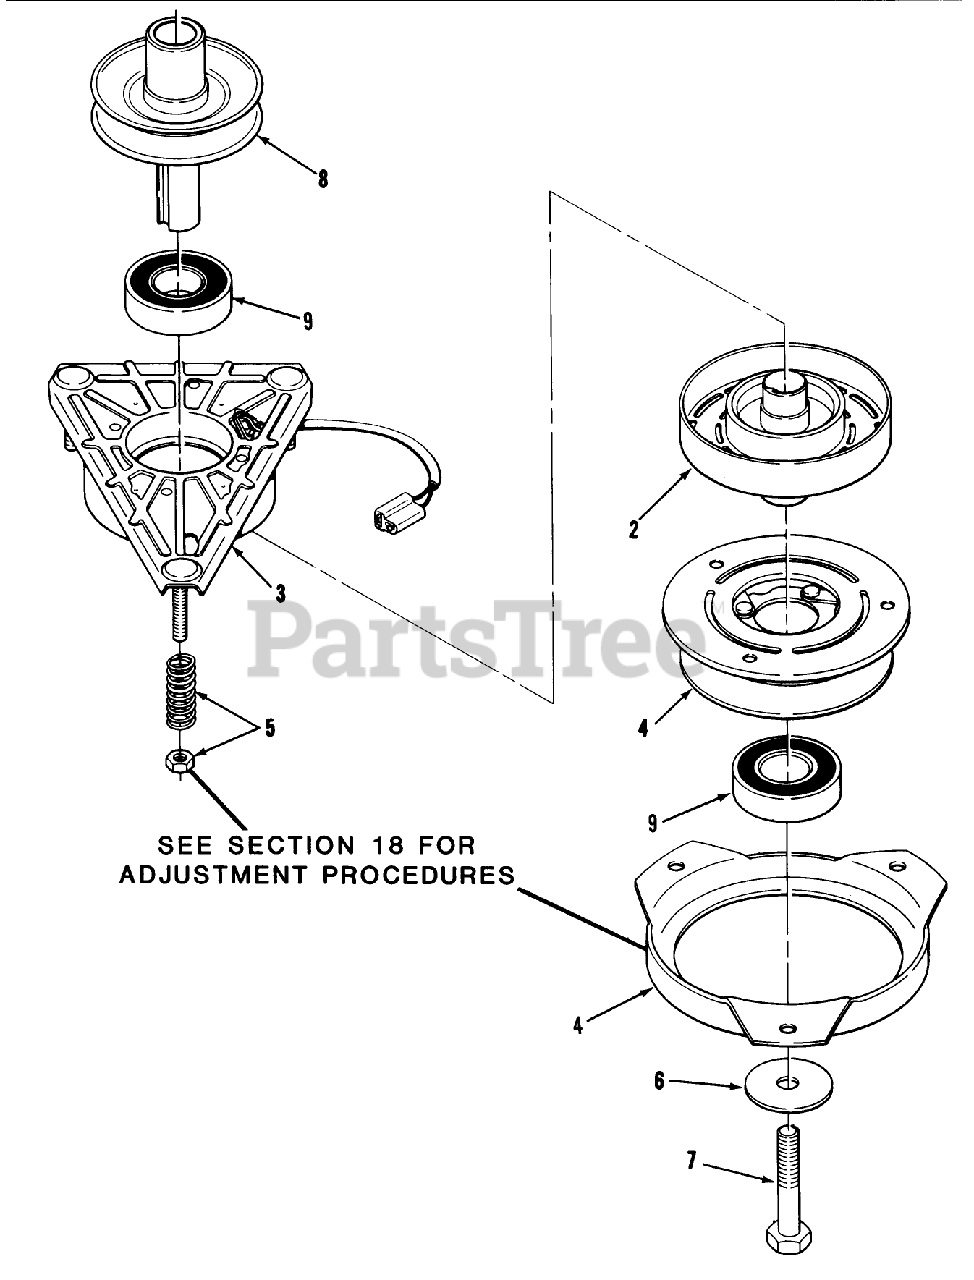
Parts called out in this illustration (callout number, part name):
1	Electric Clutch Assy (includes items 2, 3, 4 5)
4	ASS'Y-ARMATURE
5	ACCESS SPRING & NUT
6	WASHER
8	PULLEY-ENGINE
9	BEARING-ELEC CLUTCH
